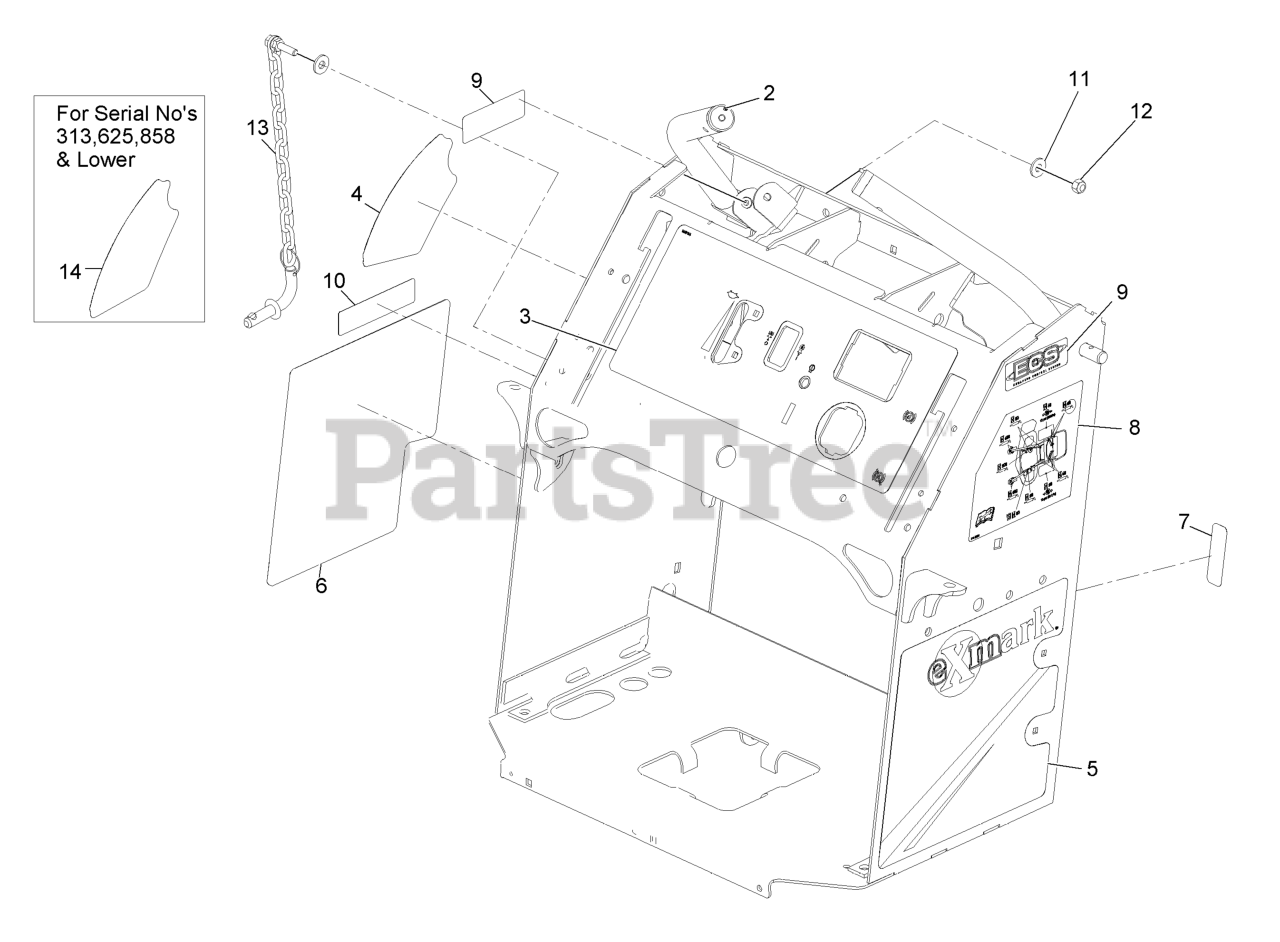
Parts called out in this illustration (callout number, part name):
3	DECAL-CONTROL PANEL EFI
4	DECAL-HEIGHT OF CUT
5	DECAL-LH PANEL
6	DECAL-RH PANEL
7	DECAL-FUSE
8	Decal-Service Aid
9	DECAL-ECS LOGO
10	DECAL-ARRESTER, SPARK
11	WASHER-FLAT
12	NUT-LOCK, NI
13	HOC PIN ASM
14	DECAL-HEIGHT OF CUT
